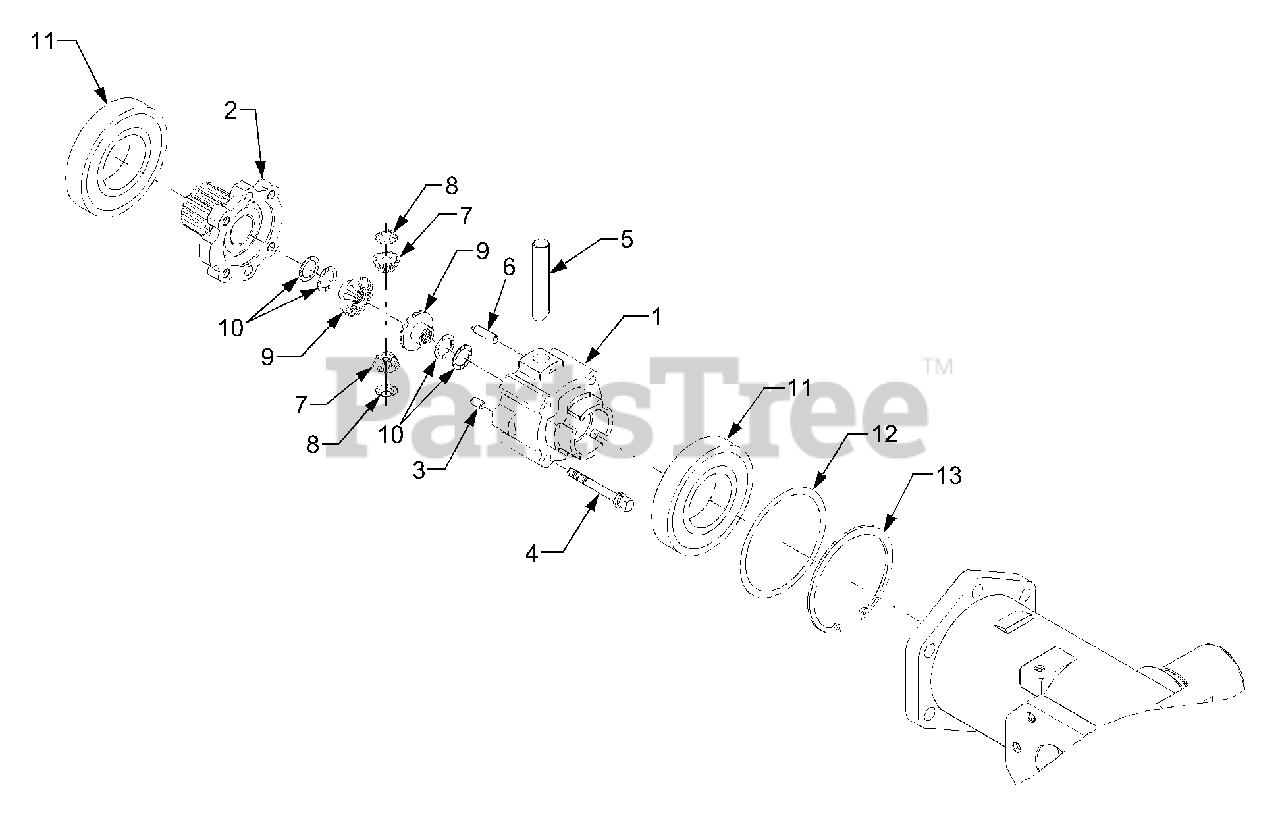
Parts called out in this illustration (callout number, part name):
1	Case, Front Differential
2	Cover, Differential Case
3	Pin, Straight
5	Shaft, Differential Pinion
6	Pin, Straight
7	Pinion, Differential
8	Washer, Differential Side
9	Gear, Differential Side
11	Bearing, Ball
